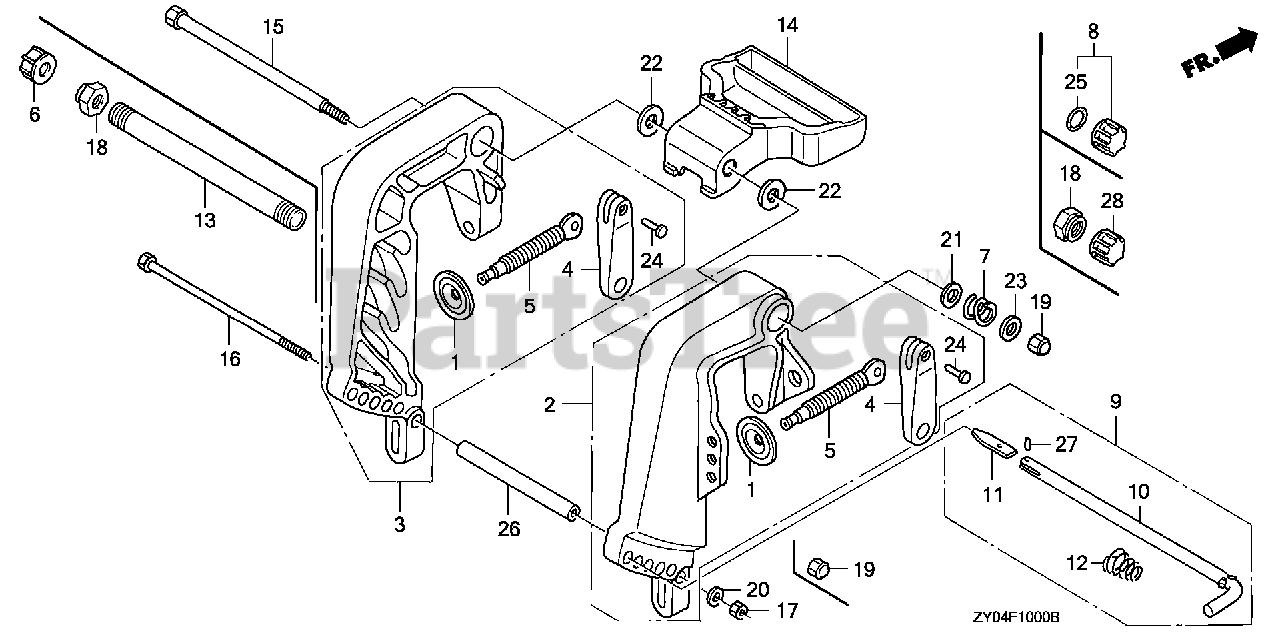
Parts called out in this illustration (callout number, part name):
1	PLATE, PUSH
2	BRACKET, R. STERN *NH282MU* (OYSTER SILVER METALLIC-U)
3	BRACKET, L. STERN *NH282MU* (OYSTER SILVER METALLIC-U)
4	GRIP, CLAMP
5	SCREW, CLAMP
6	CAP, TILTING BOLT
9	ROD, ADJUSTING
10	ROD, ADJUSTING
11	STOPPER, ROD
12	SPRING, ADJUSTING ROD
13	SHAFT, TILTING
14	HANDLE, CARRYING REMOTE
16	BOLT, HEX. (8X163)
18	NUT, SELF-LOCK (7/8-14UNF)
19	NUT, SELF-LOCK (8MM)
20	WASHER, PLAIN (8MM)
22	WASHER, WAVE (22MM)
24	RIVET (4X22.6)
25	O-RING (15.54X2.62)
26	COLLAR, DISTANCE (8MM)
27	PIN, SPRING (2.5X8)
